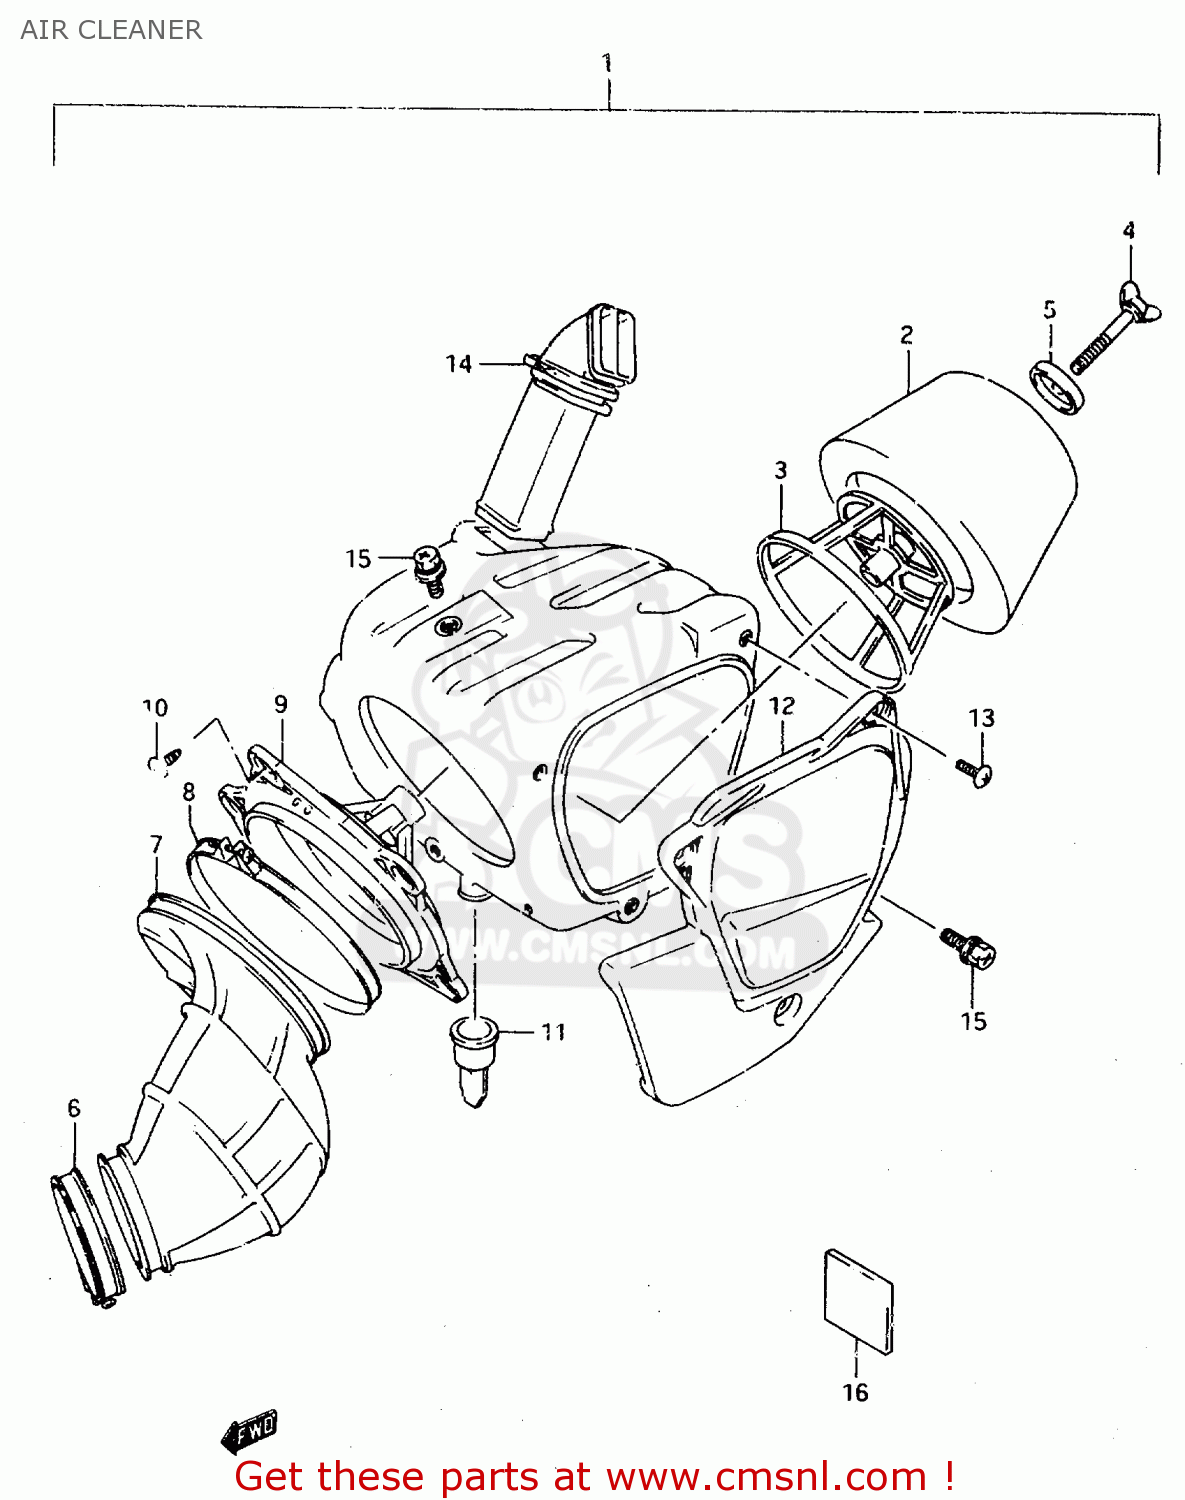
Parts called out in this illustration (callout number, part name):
1	CLEANER ASSY, AIR
2	FILTER,AIR
3	HOLDER,FILTER
4	BOLT, WING
5	WASHER,AIR CLEANER
6	CLAMP
7	TUBE,OUTLET
8	CLAMP
9	BASE,FILTER
10	SCREW
11	CAP,DRAIN
12	CAP,AIR CLEANER
13	SCREW 5X10
14	TUBE,INLET
15	BOLT
16	GUARD, HEAT
